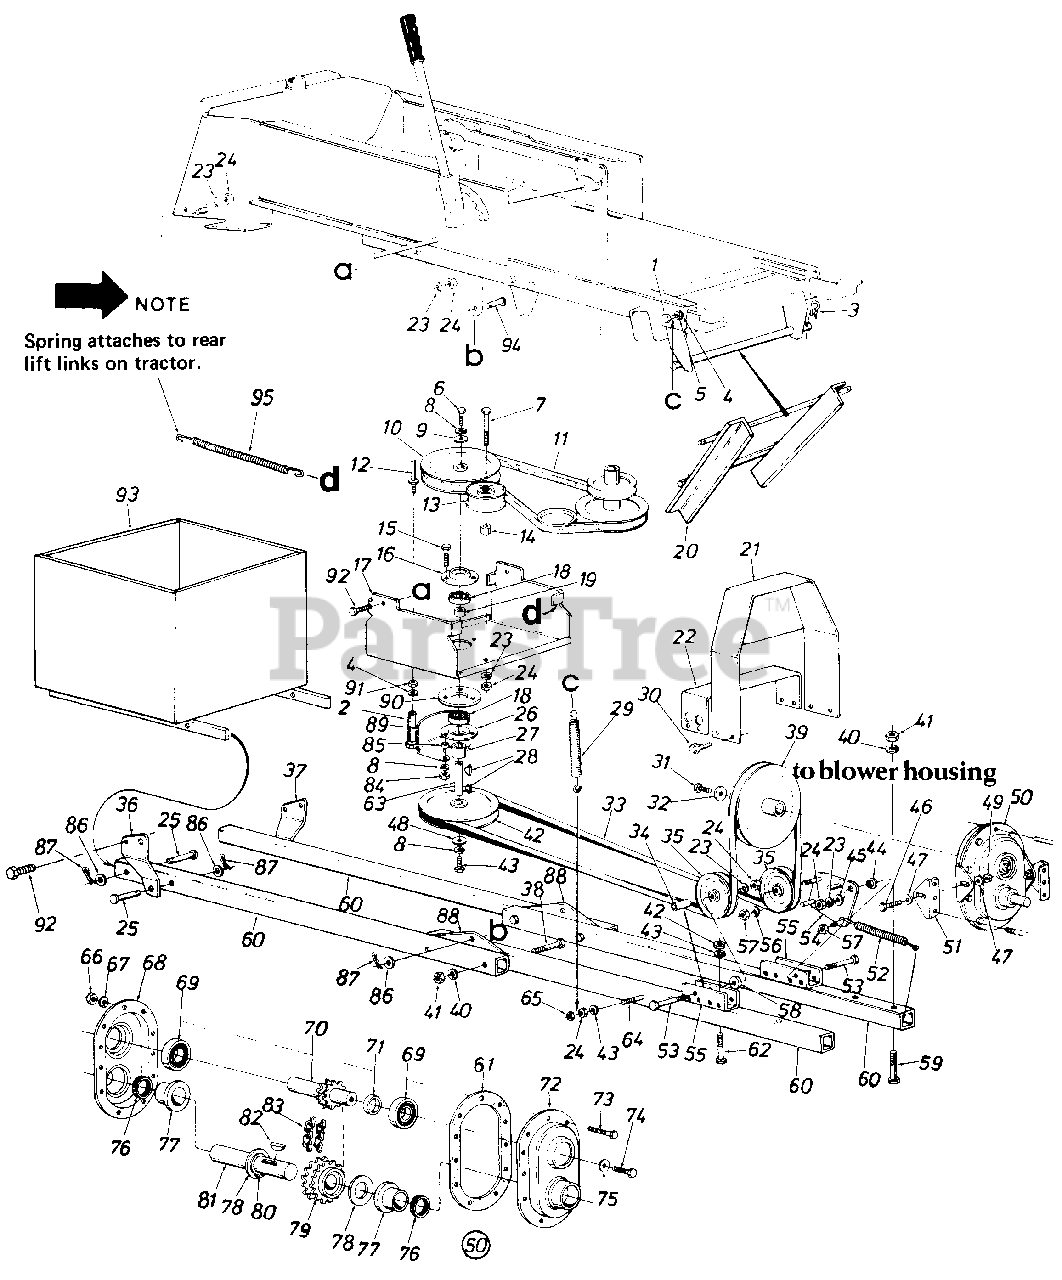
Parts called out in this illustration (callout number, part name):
1	Hex Bolt 1/4-28 x 1.50"
2	Clevis Pin Special 3/8" Dia. x 2.62" Lg.
3	Inter. Cotter Pin 1/2" Dia.
4	L.-Wash. 1/4" I.D.
5	Hex Nut 1/4-28 Thd.
6	Hex Bolt 3/8-24 x 1.0" Lg.
7	Hex BoIt 3/8-16 x 2.25" Lg.
8	L.-Wash. 3/8" I.D.
9	L.-Wash. .39" I.D. x 1.25" O.D.
10	5/8 "V"-Pulley .790" I.D. x 6.50 O.D.
11	"V"-Belt 1/2" x 52.0" Lg.
12	Belt Guard Pin 1/4" Dia. x l.68" Lg.
13	Fl.-Idler w/flanges 3.75" O.D.
14	Spacer .385" I.D. x .630" 0.D. x.760" Lg.
15	Hex BoIt 5/16-24 x 1.50" Lg.
16	Open Brg. Housing 1.85" I.D.
19	Spacer 1.0" O.D. x .790" I.D. x.350" Lg.
20	Guide Bracket Ass'y.
21	Belt Cover Ass'y.
22	Belt Cover Brkt.
23	L.-Wash. 3/8" I.D.
24	Hex Nut 3/8-15 Thd.
25	Clevis Pin .50" Dia. x 2.75" Lg.
26	Bearing Housing 1.85" I.D.
27	Spacer.80" I.D. x 1.00" O.D. x .125" Lg.
28	Hi-Pro-Key 3/16 x 5/8"
29	Extension Spring 1.00" O.D. x 6.44" Lg.
30	Hex Wash. HD. Sf. Tap Scr. 5/16-24 x .50" Lg.
31	Hex L.-Bolt 3/8-24 x 1.00" Lg.
32	Bell.-Wash. .400" I.D. x 1.25" O.D.
33	"V"-Belt 1/2" A x 112.0" Lg.
34	Spacer .39" I.D. x .62" O.D. x 1.74" Lg.
35	5/8" "V"-Belt Idler 4.00" O.D.
39	5/8" "V"-Pulley 1.00" I.D. x 7.50" O.D.
40	L.-Wash. 1/2" I.D.
41	Hex Nut 1/2-13 Thd.
42	5/8" "V"-Pulley .79" I.D. x 6.5"
43	Hex Bolt 3/8-24 x 1.0" Lg.
44	Shoulder Spacer .625" I.D.
45	Fl.-Wash. .400" I.D. x 1.25" O.D.
46	Hex Bolt 5/16-18 x .75" Lg.
47	Bell.-Wash. .345" I.D. x .88" O.D.
48	Fl.-Wash. .39" I.D. x 1.25" O.D.
49	Hex Nut 5/16-18 Thd.
50	Comp. Chain Gear Box Ass'y.
51	Gear Box Support Brkt.
52	Extension Spring .87" Dia. x 6.00" Lg.
53	Hex Bolt 3/8-16 x 3.0" Lg. (Grade 8)
56	Fl.-Wash. .385" I.D. x .87 O.D.
57	Hex Ins. L.-Nut 3/8-24 Thd.
58	Fl.-Wash. .400" I.D. x 1.25" O.D. x .157 Thk.
59	Hex Bolt 1/2-13 x 3.00" Lg.
62	Hex Bolt 3/8-16 x 3.0" Lg. (Grade 8)
63	Shaft-.787" Dia. x 3.81" Lg.
64	Hex Bolt 3/8-16 x 3.25" Lg.
65	Hex Cent. L.-Jam Nut 3/8-16 Thd.
66	Hex Nut 1/4-28 Thd.
67	Spr.-Wash. .270" I.D. x .57" O.D.
68	Gear Hsg. Half-L.H.
69	Ball Brq. 1.00" I.D. x 2.00" O.D.
70	11-2x.5 Pitch-Sprkit. Shaft Ass'y.
71	Spacer 1.00" I.D. x 1.18" O.D. x .440 Lg.
72	Gear Hsg. Half-R.H.
73	Hex Bolt 1/4-28 x 1.00" Lg. (Grade 5)
74	Hex L.-Bolt 3/8-24 x 1.00" Lg.
75	Bell.-Wash. .400" I.D. x 1.25" O.D.
76	Oil Seal 1.25" x 1.75" O.D.
77	Flange Brg. 1.252" I.D.
78	F l .-Wash. 1.25" I.D. x 2.00" O.D
79	DBL Sprkt. 19-2 Teeth x .500" Pitch
80	Snap Ring for 1.25" Dia. Shaft
81	Gear Shaft 1.25" Dia. x 6.0" Lg.
82	#A Hi-Pro Key 1/4 x 7/8" Dia.
83	40-2 Chain 1/2" Pitch x 25 Links
84	Hex Nut 5/16-24 Thd.
85	Spacer .380" I.D. x .625" O.D. x.227" Lg.
86	Fl.-Wash. .510" I.D. x 1.0" O.D.
87	Inter. Cot.-Pin 1/2" Dia.
91	Hex Nut 1/4-20 Thd.
92	Hex Bolt 3/8-16 x 1.0" Lg.-Gr. 5
93	Weight Box Ass'y.
95	Ext. Spring
